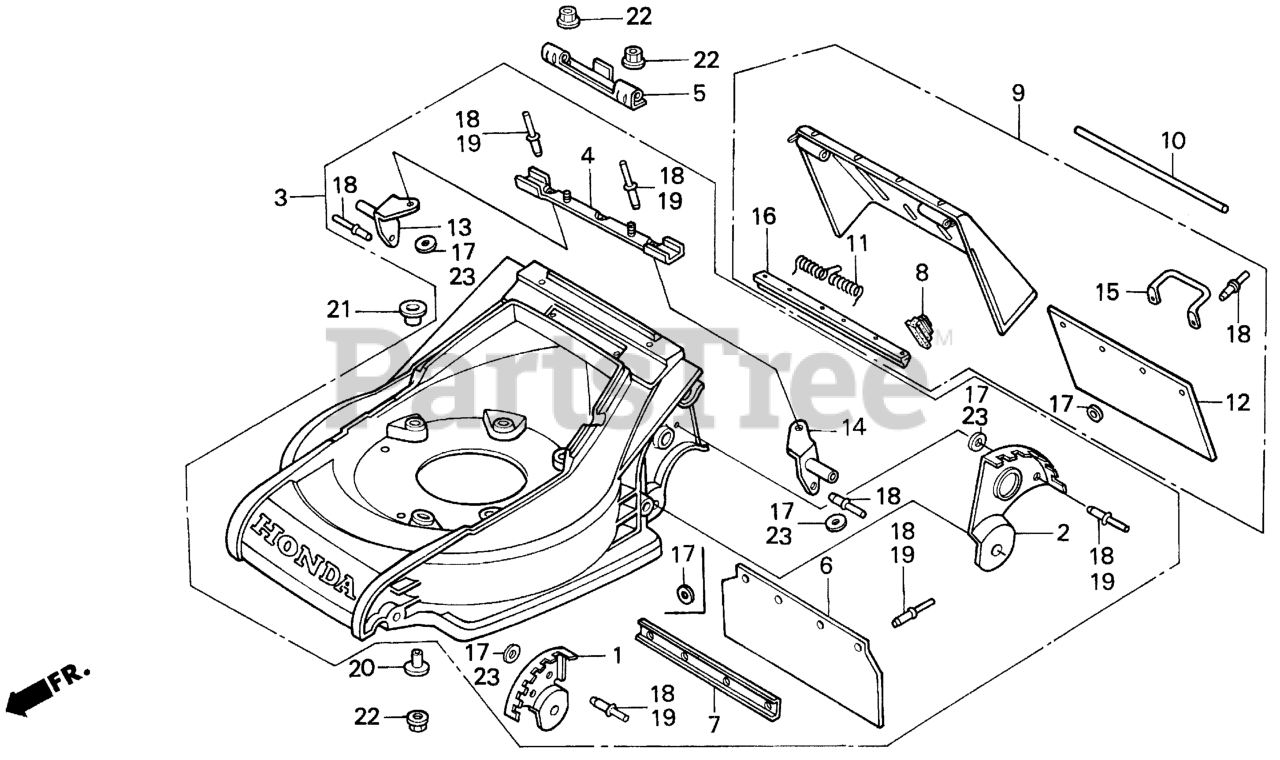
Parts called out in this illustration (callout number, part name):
1	PANEL, FR. ADJUSTING
2	PANEL, RR. ADJUSTING
3	HOUSING, CUTTER *NH246* (LOOSY GRAY)
4	HINGE, DISCHARGE GUARD (NOT AVAILABLE)
5	HINGE, DISCHARGE GUARD (NOT AVAILABLE)
6	SHIELD, SAFETY
7	PLATE, SAFETY SHIELD
8	STOPPER, DISCHARGE GUARD
9	GUARD, DISCHARGE (NOT AVAILABLE)
10	SHAFT, DISCHARGE GUARD
11	SPRING, GUARD RETURN
12	SHIELD, DISCHARGE GUARD (NOT AVAILABLE)
12	SHIELD, DISCHARGE GUARD
13	STAY, R. HANDLE
14	STAY, L. HANDLE
15	GRIP, DISCHARGE GUARD (NOT AVAILABLE)
16	SEAL, DISCHARGE GUARD (NOT AVAILABLE)
17	WASHER, STOPPER (14MM)
17	WASHER, STOPPER
18	RIVET, BLIND (4.8MM)
19	RIVET, BLIND (4.8X18.2) (NOT AVAILABLE)
20	COLLAR, ENGINE BED
22	NUT, FLANGE (6MM)
23	WASHER, PLAIN (5MM)
